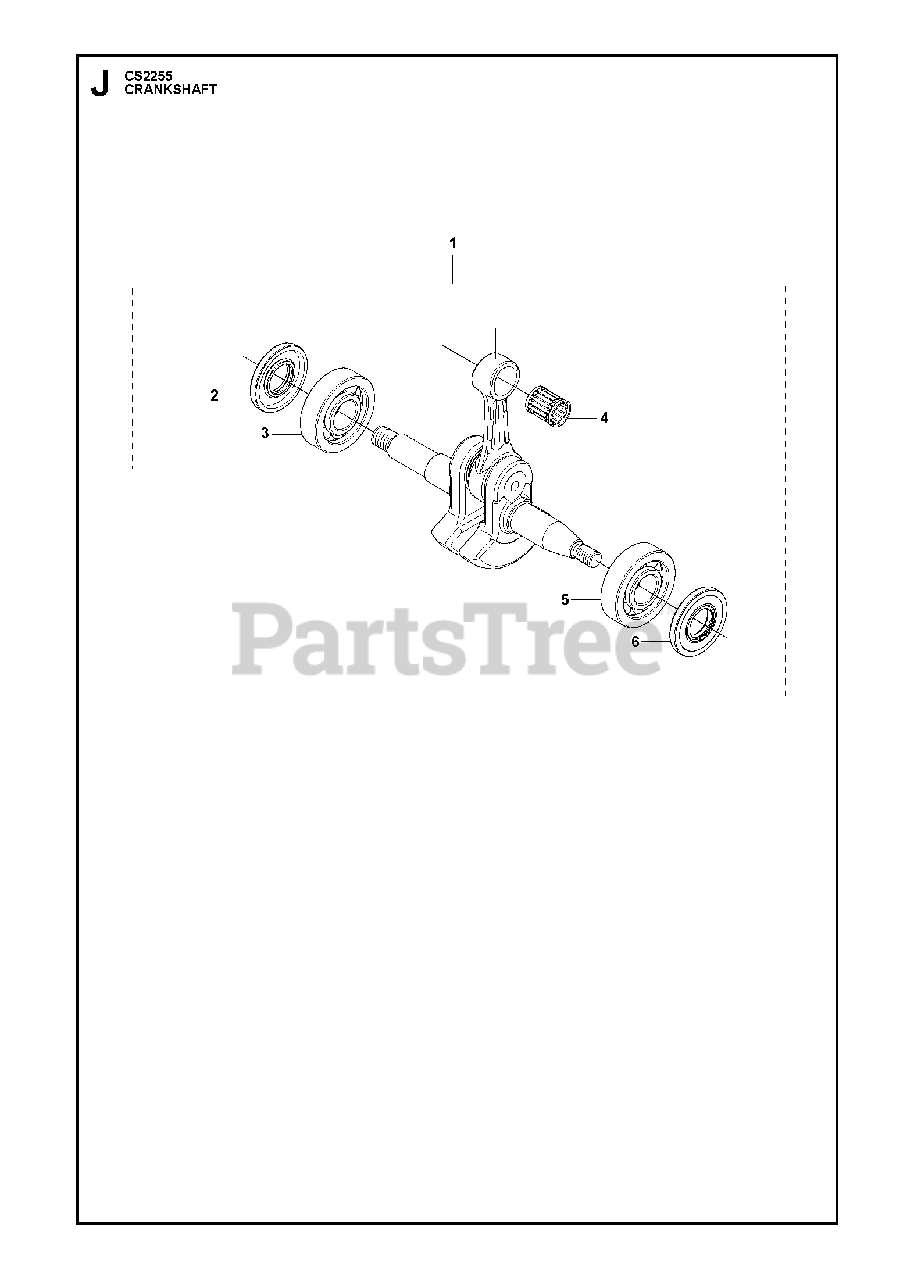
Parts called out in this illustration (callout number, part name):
1	RP CRANKSHAFT CPL
2	COVER
3	BEARING
4	SUPPORT BUSHING
5	BEARING
6	COVER
